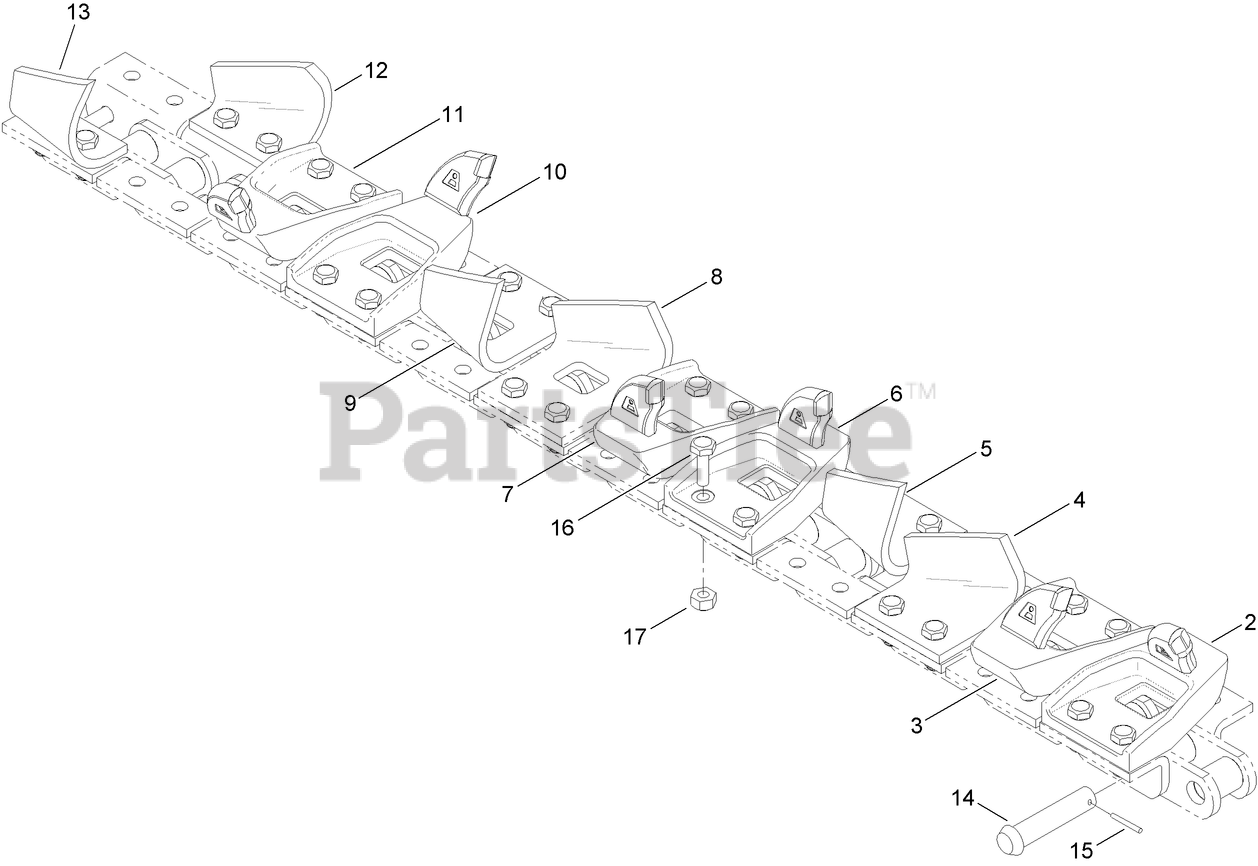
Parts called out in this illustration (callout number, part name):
2	TOOTH-SHARK (1" L)
3	TOOTH-SHARK (1" R)
4	TOOTH-CUP (1"-8" L)
5	TOOTH-CUP (1"-8" R)
6	TOOTH-SHARK (3" L)
7	TOOTH-SHARK (3" R)
8	TOOTH-CUP (3" L)
9	TOOTH-CUP (3" R)
10	TOOTH-SHARK (6" L)
11	TOOTH-SHARK (6" R)
12	TOOTH-CUP (6" L)
13	TOOTH-CUP (6" R)
14	PIN-MASTER
15	PIN-KEEPER, MASTER
17	NUT-LOCK
